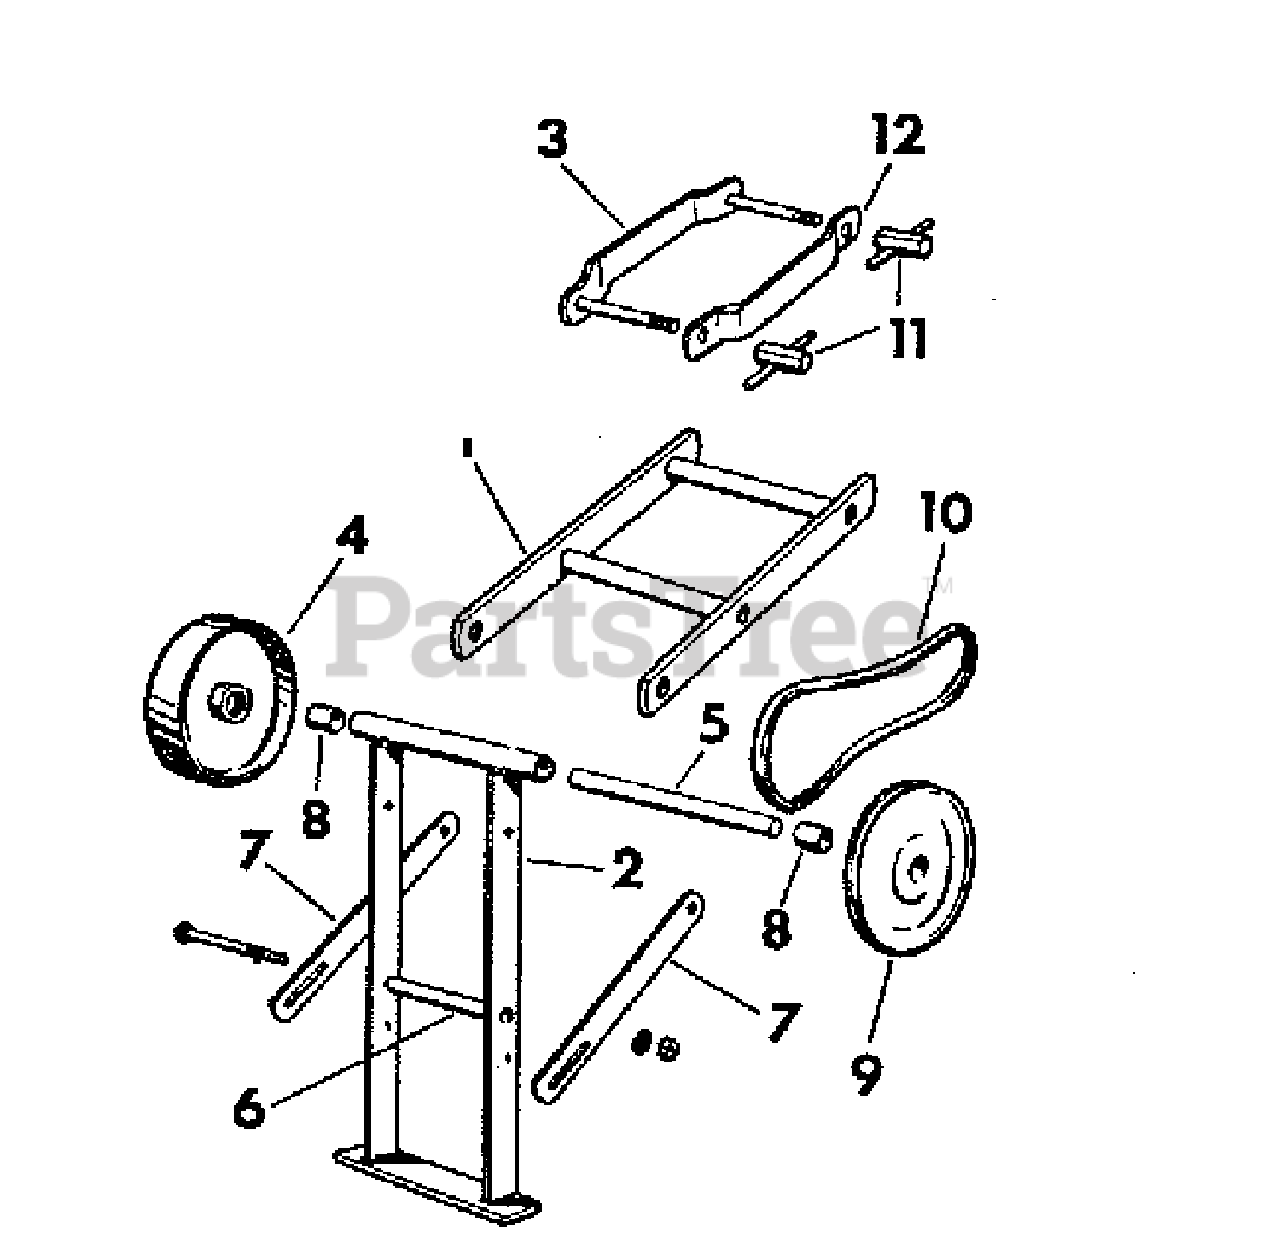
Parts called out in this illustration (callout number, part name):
2	BRACKET, Bearing
3	CLAMP, Hitch
5	COUNTERSHAFT
9	TRANSMISSION, Sheave, Iron or Steel
11	WING NUT, Complete
12	SIDE PLATE, Hitch
